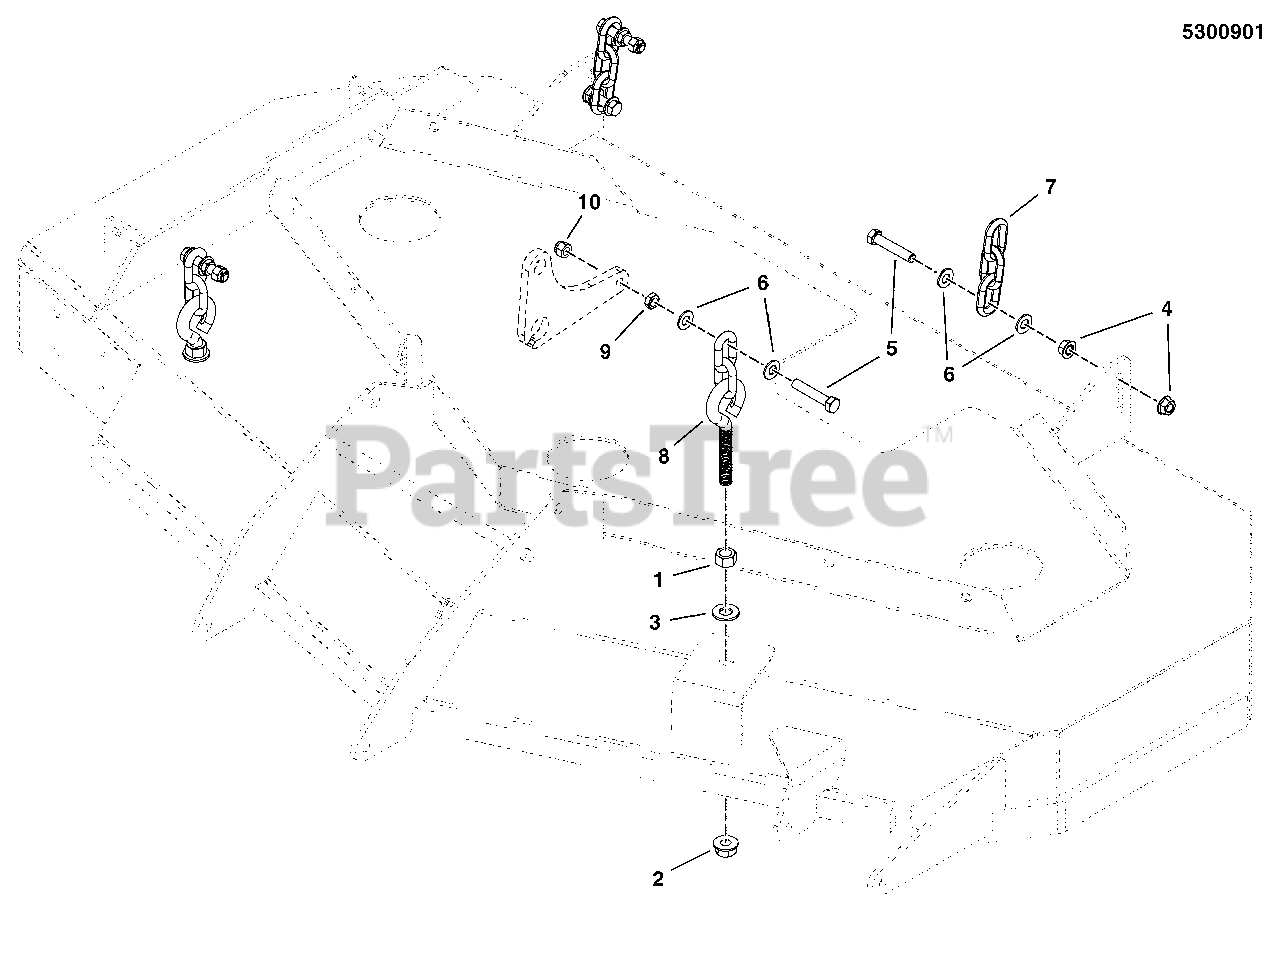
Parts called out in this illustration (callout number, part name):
1	NUT, 1/2-13 HEX
2	NUT, Hex Flange, Nylock, 1/2-13
3	WASHER, 1/2 SAE
4	NUT, 3/8-16 HEX SERRATED FLANGE
5	BOLT, 3/8-16 X 2, GD5, CZ
6	WASHER, 3/8 SAE
7	CHAIN, 5/16 GD30, 3 LINKS
8	HANGER, FRONT DECK-2LINK, 5.5" EB
9	NUT, 3/8-16 HEX JAM
10	NUT, 3/8-16 HEX NYLON LOCK
